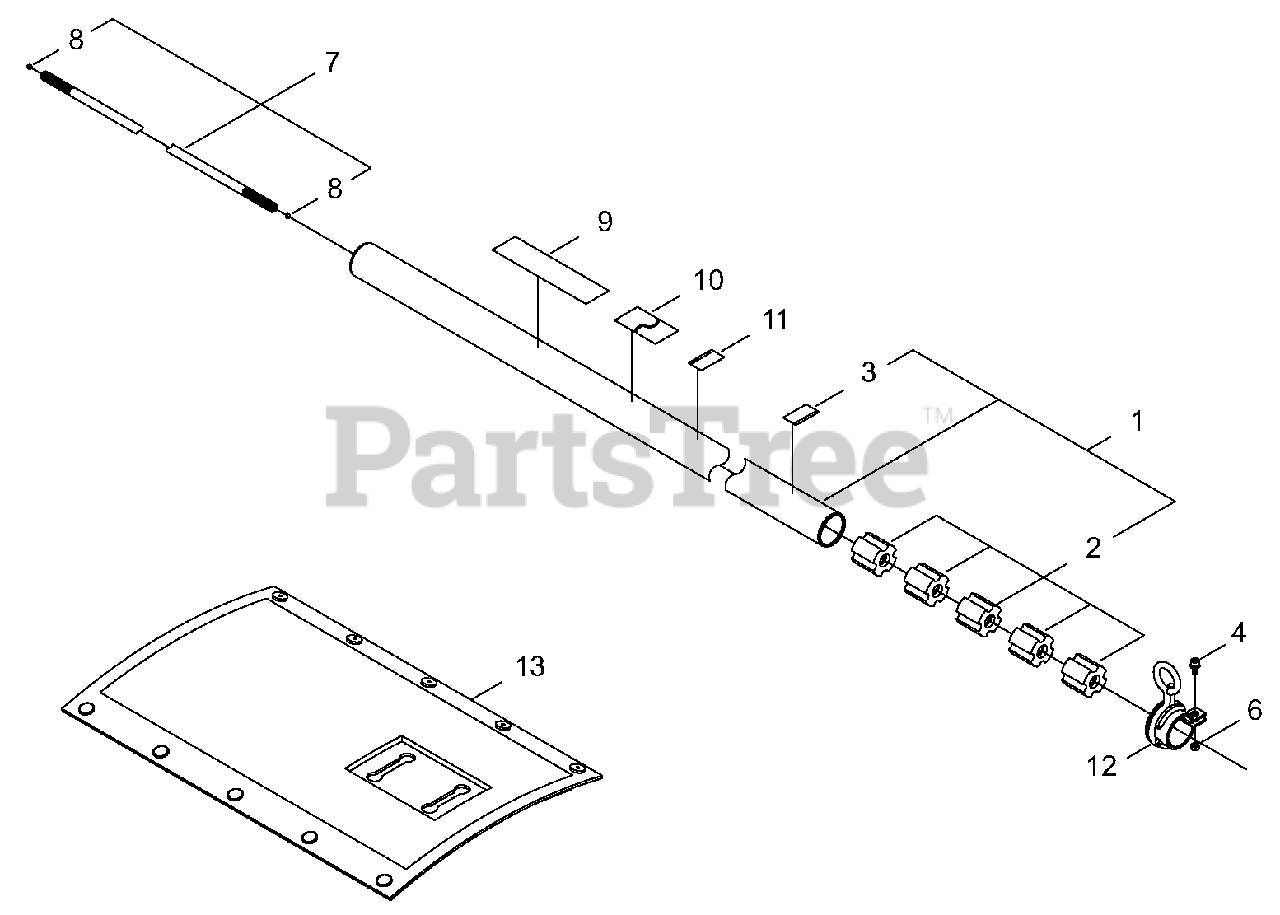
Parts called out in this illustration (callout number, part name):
1	MAIN PIPE ASSY
2	BUSHING
3	LABEL - ALIGNMENT
4	SCREW - 5X12
5	LOCKWASHER - 5
6	NUT - 5
7	DRIVESHAFT ASSY
8	STOPPER
9	LABEL - SHINDAIWA PROFESSIONAL
10	LABEL - CAUTION
11	LABEL - HANDLE LOCATION
12	HANGER ASSY
13	PROTECTOR
